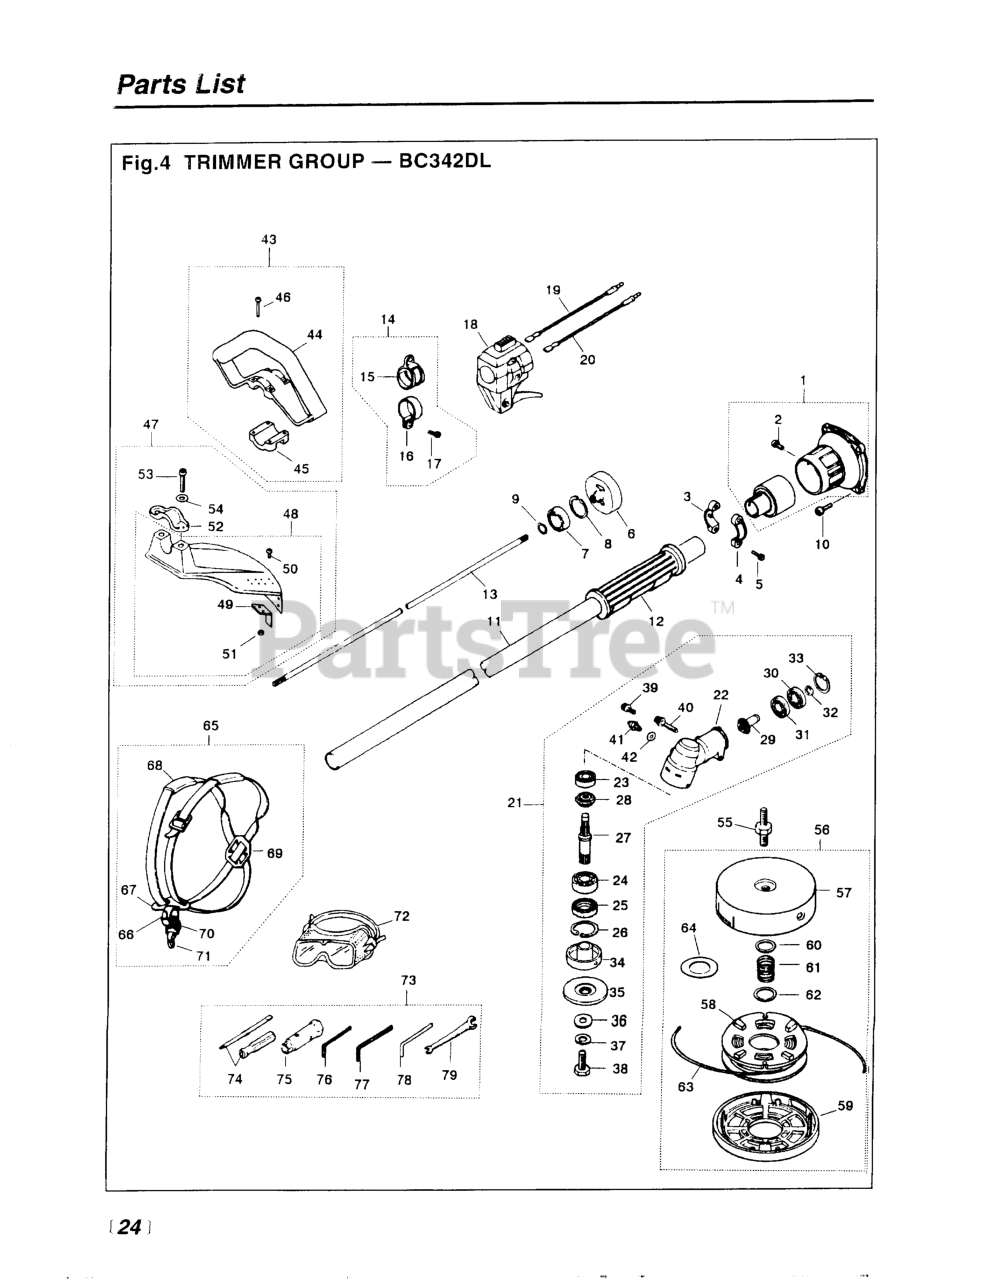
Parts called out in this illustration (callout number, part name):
1	HOUSING ASSY (RPLS-11100)
2	SCREW, M6 x 10
3	CLAMP, RIGHT (RPLS -11130)
4	CLAMP, LEFT (RPLS-11140)
5	BOLT
6	DRUM, CLUTCH
7	BEARING
8	RING, SNAP, M35 X 1.5
9	RING, SNAP, M15 X 1.0
10	BOLT, M6 x 20
13	SHAFT, SPLINE
14	HANGER ASSY. (NLA)
15	HANGER
16	CLAMP
17	SCREW, M5 x 25
19	CORD-A, BLACK
20	CORD-B, RED
21	GEARCASE (RPLS-13005)
22	GEARCASE (RPLS -13113)
23	BEARING (RPLS T3403-13510)
25	SEAL, OIL
26	RING, SNAP, M32 x 1.2
27	SHAFT, GEAR
28	GEAR, BEVEL
31	BEARING (RPLS T3403-13510)
32	RING, SNAP
33	RING, SNAP, M26 X 1.2
34	HOLDER (A)
35	HOLDER (B)
36	WASHER, M8 x 2.3 (RPLS -20823)
37	WASHER (RPLS 3180-13270)
38	BOLT, LH
39	BOLT, M5 X 10
40	BOLT, M6 x 1.35
41	FITTING, GREASE
42	WASHER, M6 X .8
43	HANDLE ASSEMBLY
44	HANDLE
45	CLAMP
46	SCREW, M5 x 35
47	GUARD ASSY (RPLS -24001)
48	GUARD COMP.
49	BLADE
50	SCREW, M5 x 12
51	NUT
52	CLAMP
53	BOLT, M6 x 1.30
54	WASHER, M6 X 15
55	ARBOR, 8MM
56	6
59	COVER
60	PLATE, LARGE
62	PLATE, SMALL
63	CORD
64	SPACER
65	HARNESS ASSY (USE 6565-17200)
68	PROTECTOR
71	HOOK COMP (RPLS -96414)
73	TOOL SET
74	SCREWDRIVER
76	WRENCH (TOOL)
77	WRENCH (TOOL)
78	BAR
79	SPANNER, 8 X 10 (RPLS 2540- )
